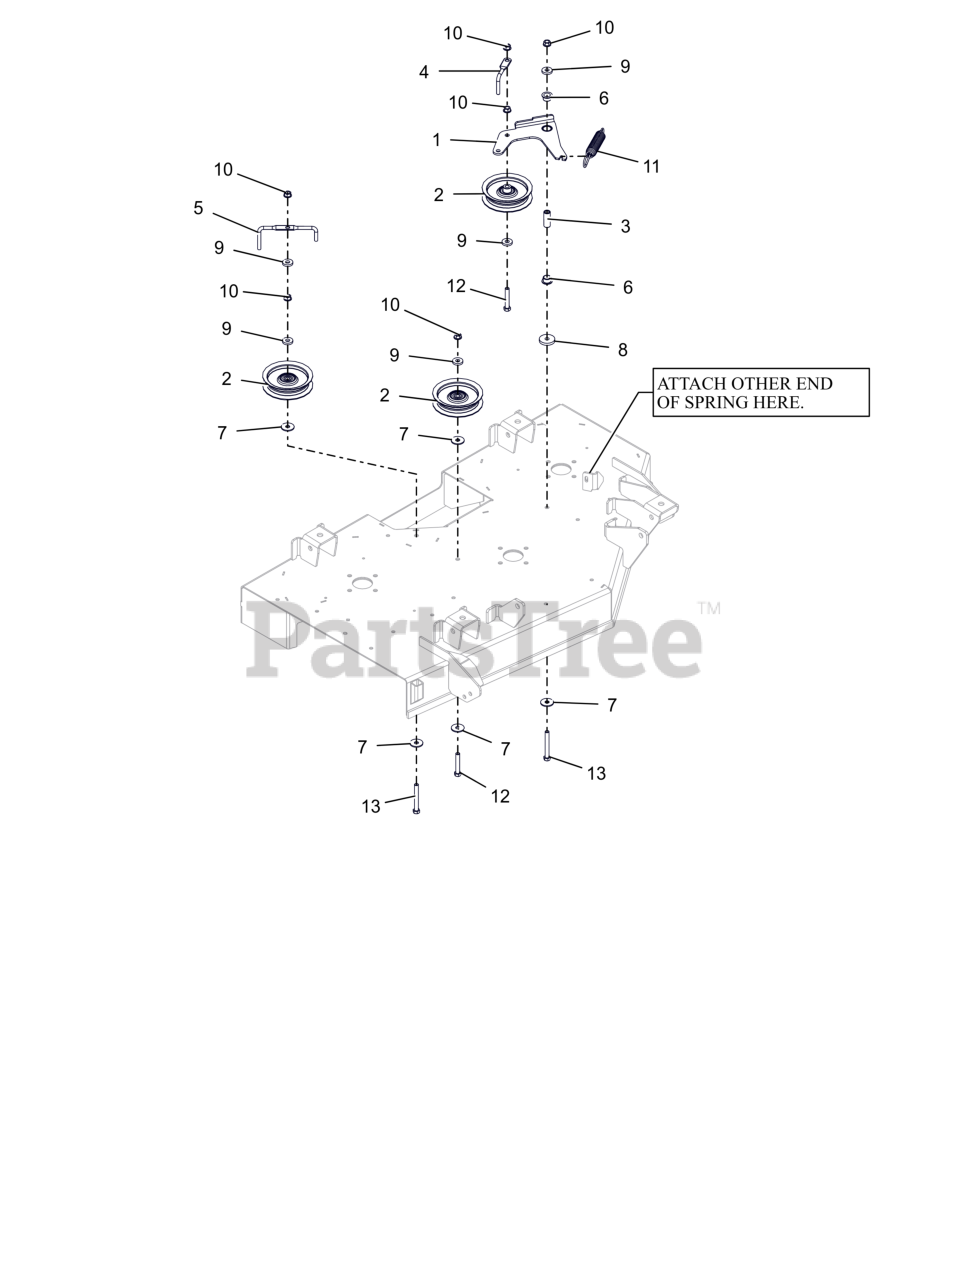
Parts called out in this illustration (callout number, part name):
1	WLDMT, IDLER ARM-42"
2	IDLER, FLAT - 4.06" X .75"
3	SPACER, .375IDX.625ODX1.66 PM
4	WIREFORM-BELT FINGER
5	BELT FINGER
6	BSHG-FLG, .625X.750X.500X1.00
7	WSHR FL STL .406X1.25X.10ZC120
8	WSHR, FLT .406X1.50X.245 ZCC
9	WSHR, FLT .406X1.00X.188 ZCC
10	NUT-LK-CTR-FLG .375-16 GF ZCC
11	SG-TENS .135X.98X6.0 WLD 62
12	BLT,HEX .38-16X2.25 G5 ZCC
13	BLT, HEX .38-16X3.00F G5 ZCC
